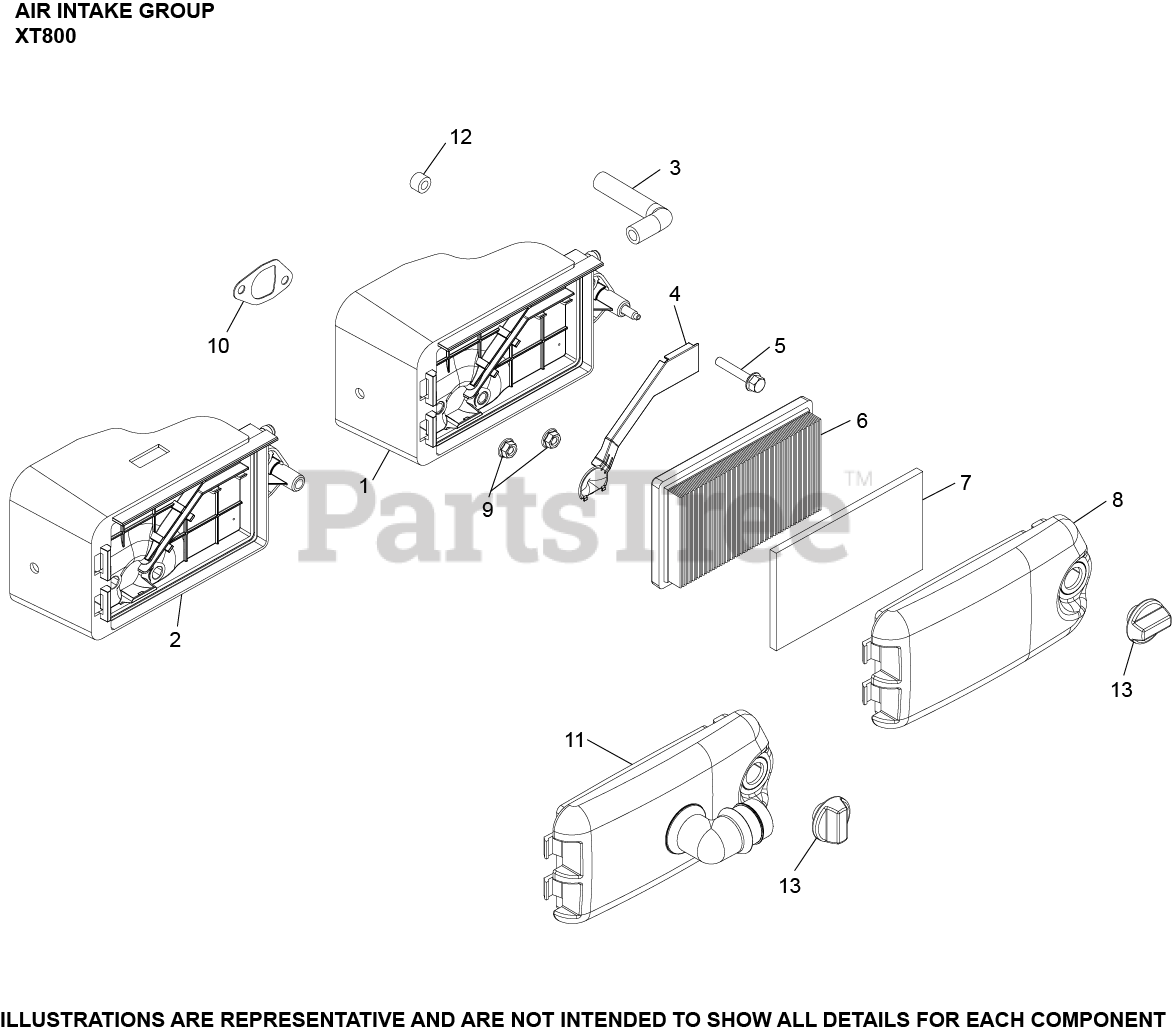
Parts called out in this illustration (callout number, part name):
1	KIT, AIR CLEANER BASE
3	HOSE, BREATHER
4	COVER, A/C BASE (BREATHER GAS)
5	SCREW, HEX FLANGE (M6) - USE 25 086 435-S
6	ELEMENT, AIR CLEANER USE 14 083 19-S
7	ELEMENT, PRE-CLEANER
8	COVER, AIR CLEANER
9	NUT, HEX FLANGE (M6) - USE 14 100 16-S
10	KIT, INTAKE GASKET
13	KNOB USE 14 341 07-S
